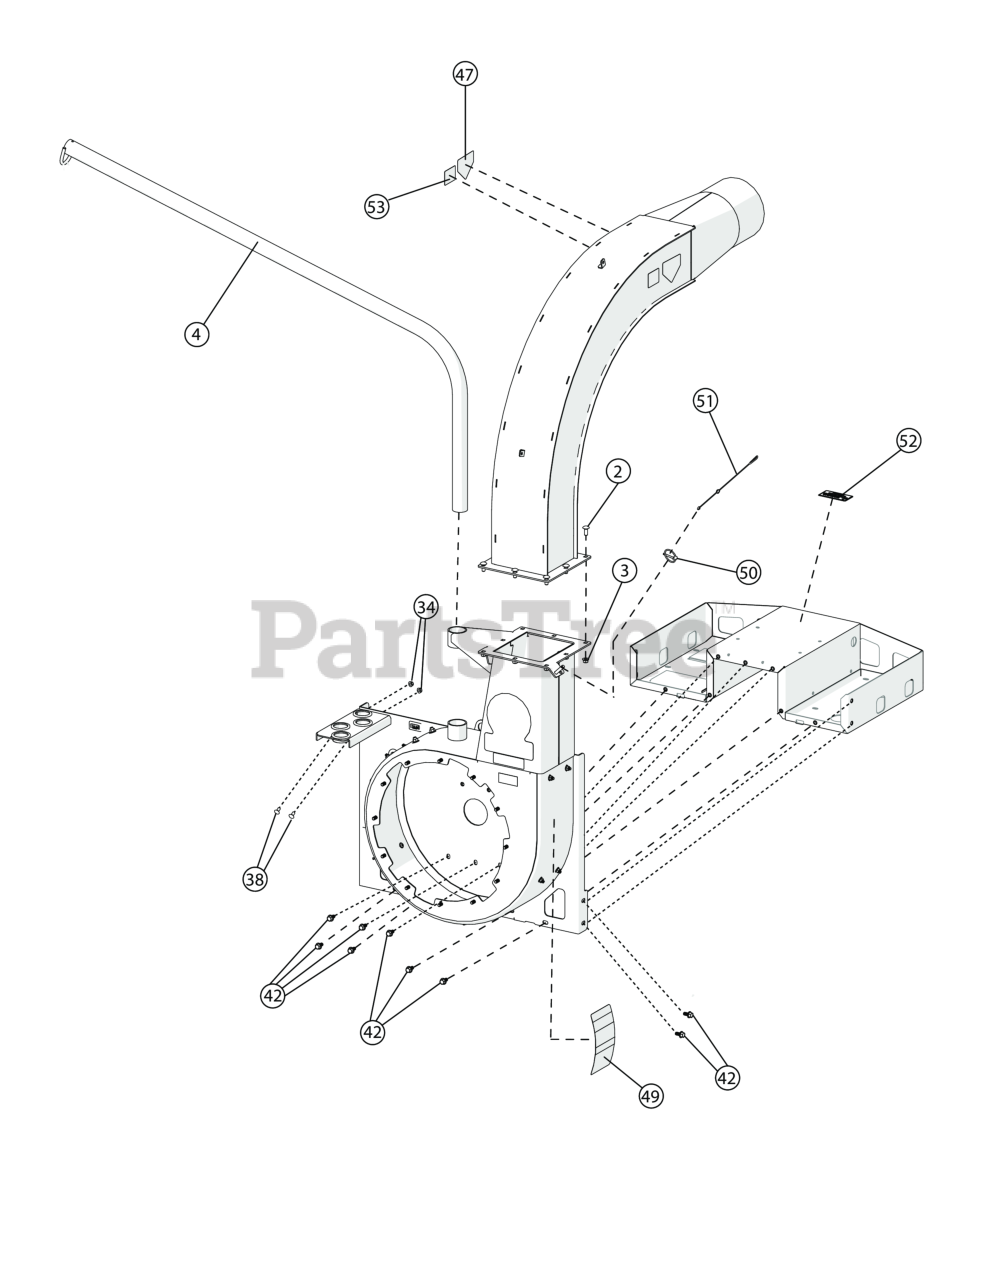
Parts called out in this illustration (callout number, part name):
2	BOLT CARRAIGE 3/8-16 X 1" ZP
3	NUT-HEX-NYLK, FLG .375"-16 ZP
4	BOOM HOSE
34	NUT-HEX-NYLK, FLG .3125-18 ZP
38	BOLT CARRIAGE 5/16"-18 X 3/4" ZP
42	SER HEX WASHER 3/8" - 16
47	LABEL WARNING OPEI
49	LABEL QL INSTRUCTION/WARN
50	LYNCH PIN 3/16" X 1 9/16"
51	LANYARD PLASTIC 10"
52	LABEL WARNING SECURE
53	LABEL DANGER FLYING DEBRIS
